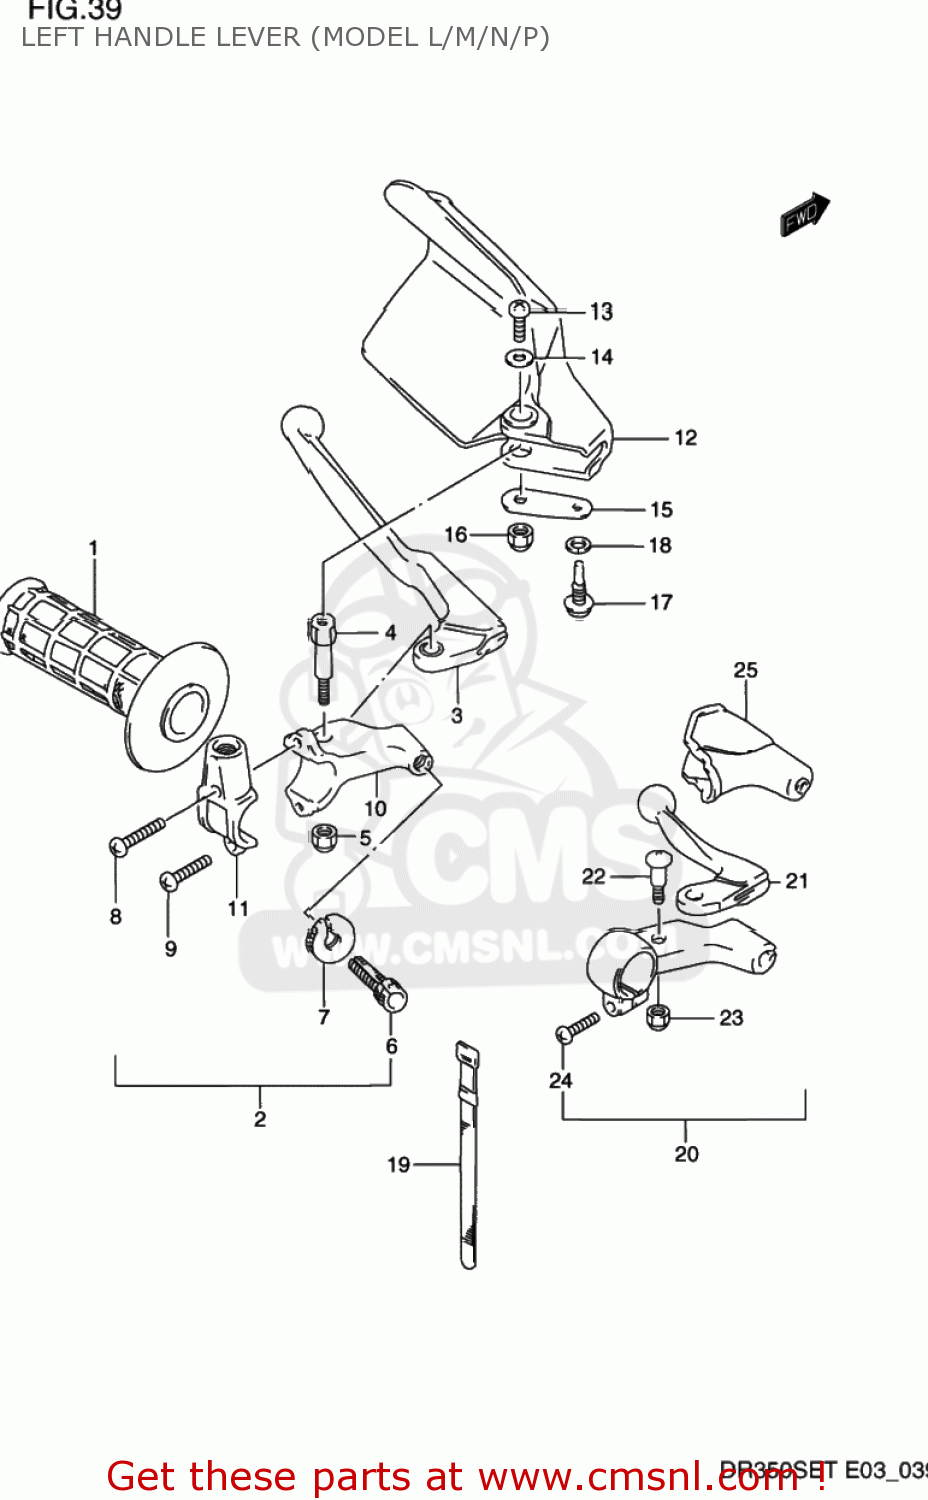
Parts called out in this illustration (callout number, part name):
1	GRIP,L
2	LEVER ASSY,CLUTCH
3	LEVER,CLUTCH
4	BOLT,LEVER SET
5	NUT 6MM
6	ADJUSTER,CABLE
7	NUT,LOCK
8	SCREW
9	SCREW(5X14)
10	HOLDER,CLUTCH LEVER
11	BRACKET,HOLDER
12	COVER,KNUCKLE,L
13	SCREW(5X10)
14	WASHER (5.5X16X1.2)
15	PLATE,KNUCKLE COVER,L LWR
16	NUT 6MM
17	SCREW
18	WASHER,LOCK
19	CLAMP(L:120)
20	LEVER ASSEMBLY,DECOMPRESSION
21	LEVER,DECOMP
22	BOLT,LEVER PIVOT
23	NUT
24	SCREW
25	COVER,DECOMP LEVER DUST
